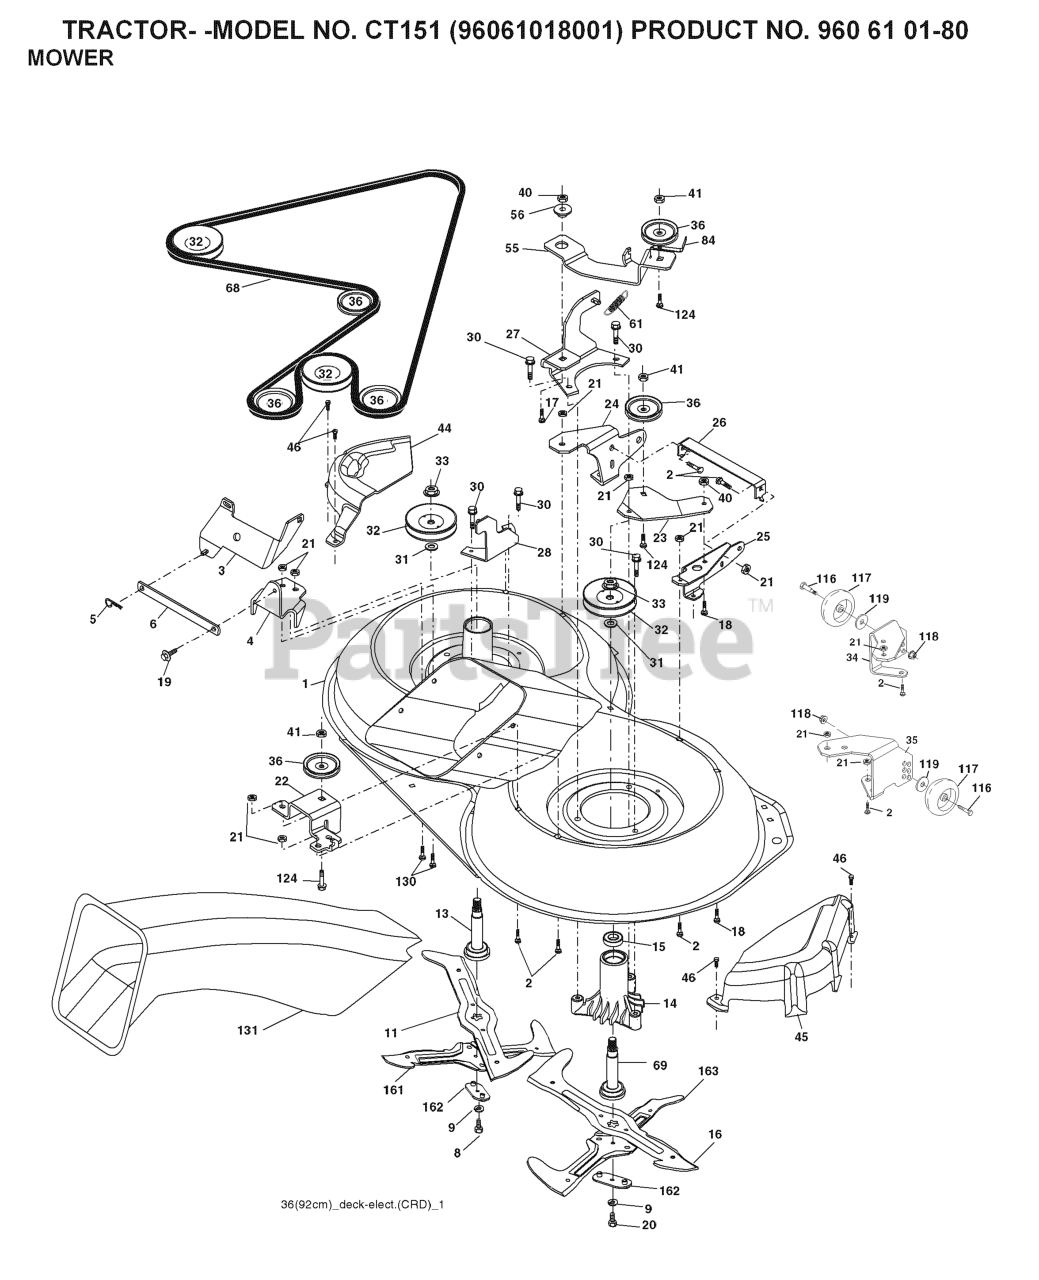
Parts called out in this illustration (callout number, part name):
2	RP BOLT 5/16-18 X3/4 ZN/YEL GR
5	RETAINER-SPRNG RB
6	BAR.SWAY.92.CRD
8	BOLT.3/8-24X1.25 GR8
9	LOCKWASHER
10	WASHER.BLADE
13	SHAFT ASM VENT
14	HOUSING.MANDREL.VENTED (MACHD)
17	BOLT.3/8-14X1.25
19	BOLT SHD 5/16-18
20	BOLT.3/8-24X1.25GR8. LHTHRD
21	LOCKNUT
26	SUPPORT
30	SCREW, WASHER HEAD
31	WASHER.SPACER.MANDREL
32	PULLEY MANDREL
33	NUT.FLANGE.LOCK.TOP
36	PULLEY.IDLER.4.25
41	NUT LOCK FLG 3/8-16 UNC
45	COVER.MANDREL.RH.CRD
46	SCREW.1/4-20X5/8
55	ARM.IDLER.92 CRD.2006
56	SPACER.RETAINER.MOWER
61	SPRING
68	BELT.DRIVE.92CM.CRD.2006
69	SHAFT.ASM.W/LWR.BRG.RH.THREAD
84	KEEPER, BELT IDLER
116	BOLT.SHOULDER.3/8-16X3-5/8.
117	RP WHEEL. GUAGE RALLY
118	NUT LOCK FLG 3/8-16 UNC
119	WASHER
124	BOLT.3/8-16X1.50
130	BOLT.CARR.SQNK.5/16-18UNC.X3/4
131	CHUTE BAGGER
254	SCREW 3/8-16X1
296	BOLT
297	NUT CENTERLOCK
